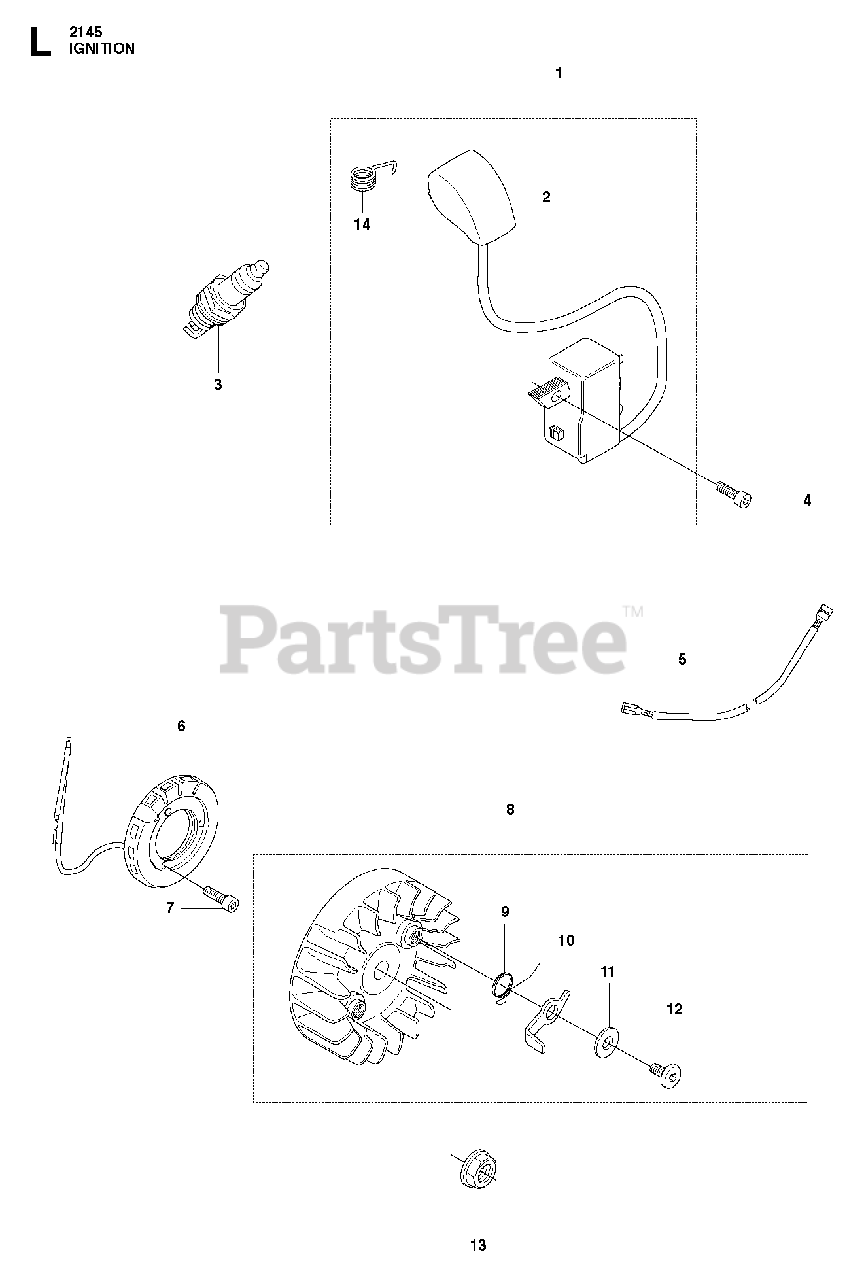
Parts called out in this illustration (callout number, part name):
1	IGNITION MODULE
2	SPARK PLUG CONNECTOR
3	SPARK PLUG RCJ6Y NLA
5	SHORTING LEAD
6	GENERATOR
7	SCREW
8	FLYWHEEL
9	SPRING
10	STARTER PAWL
11	WASHER
12	PIN, STARTER CATCH
13	NUT W/ WASHER
14	SPRING
